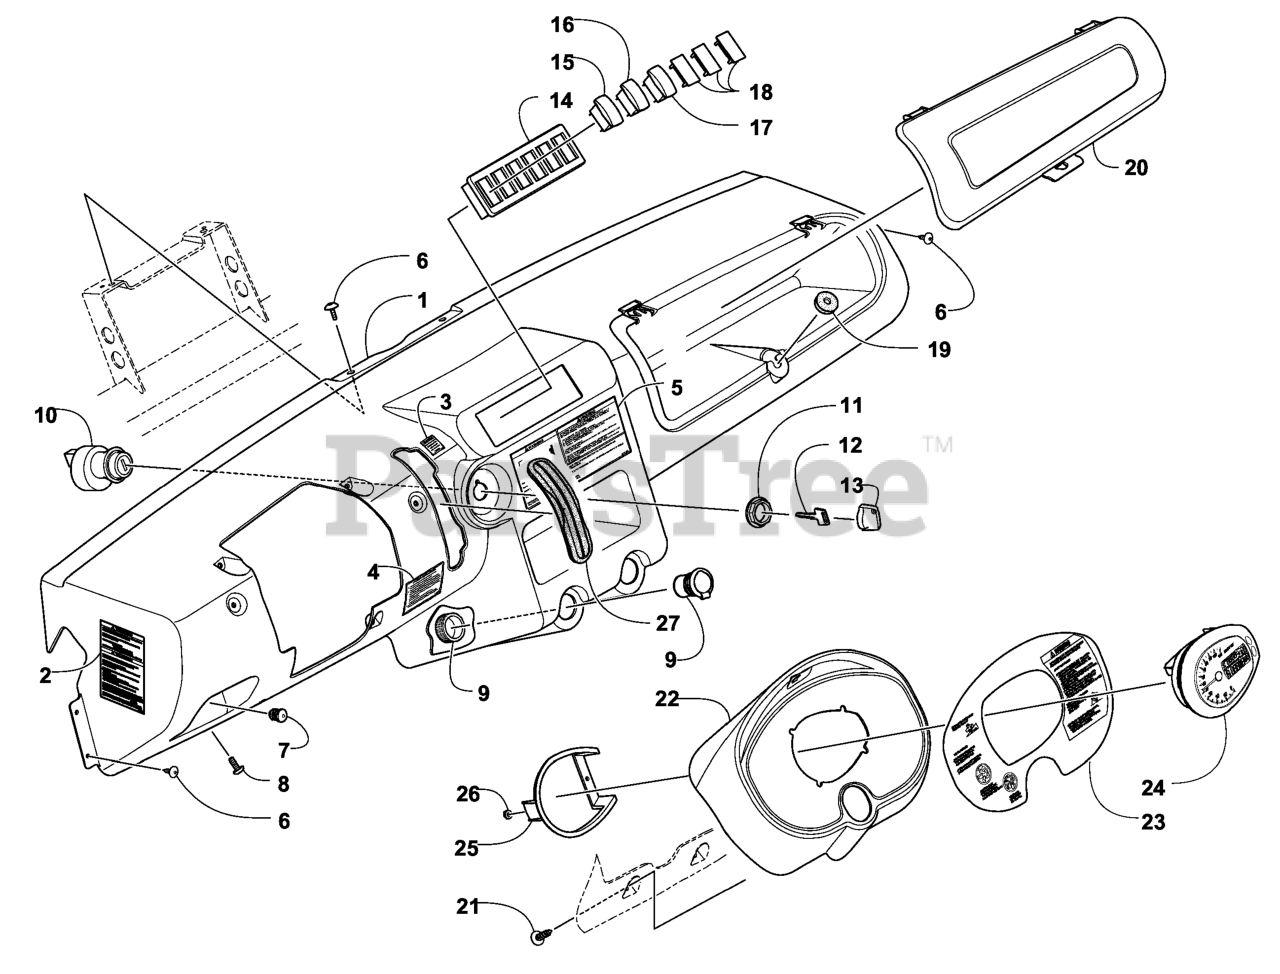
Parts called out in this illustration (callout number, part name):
1	PANEL-DASH, NON TILT/DASH
2	DECAL-WARNING, TIRE PRESS
3	DECAL-CAUTION, ENGINE RPM
4	DECAL-STARTING INSTRUCTIO
5	DECAL-WARNING, DASH CENTE
6	SCREW-TSTRH, SELFTAP
7	PLUG-TUBE
9	OUTLET-12V DC
10	SWITCH-IGNITION, START
12	KEY-BLANK
13	COVER-KEY
14	PANEL-SWITCH MOUNT
15	SWITCH-LIGHTS
17	SWITCH-REVERSE, OVERRIDE
18	PLUG-SWITCH HOLE
19	GROMMET-LATCH, GLOVE BOX
20	COVER-GLOVE BOX
21	SCREW-SELF TAPPING
22	POD-INSTRUMENT
23	DECAL-WARNING, DASH
25	CLAMP-PLASTIC
27	KIT-SHIFT BOOT
